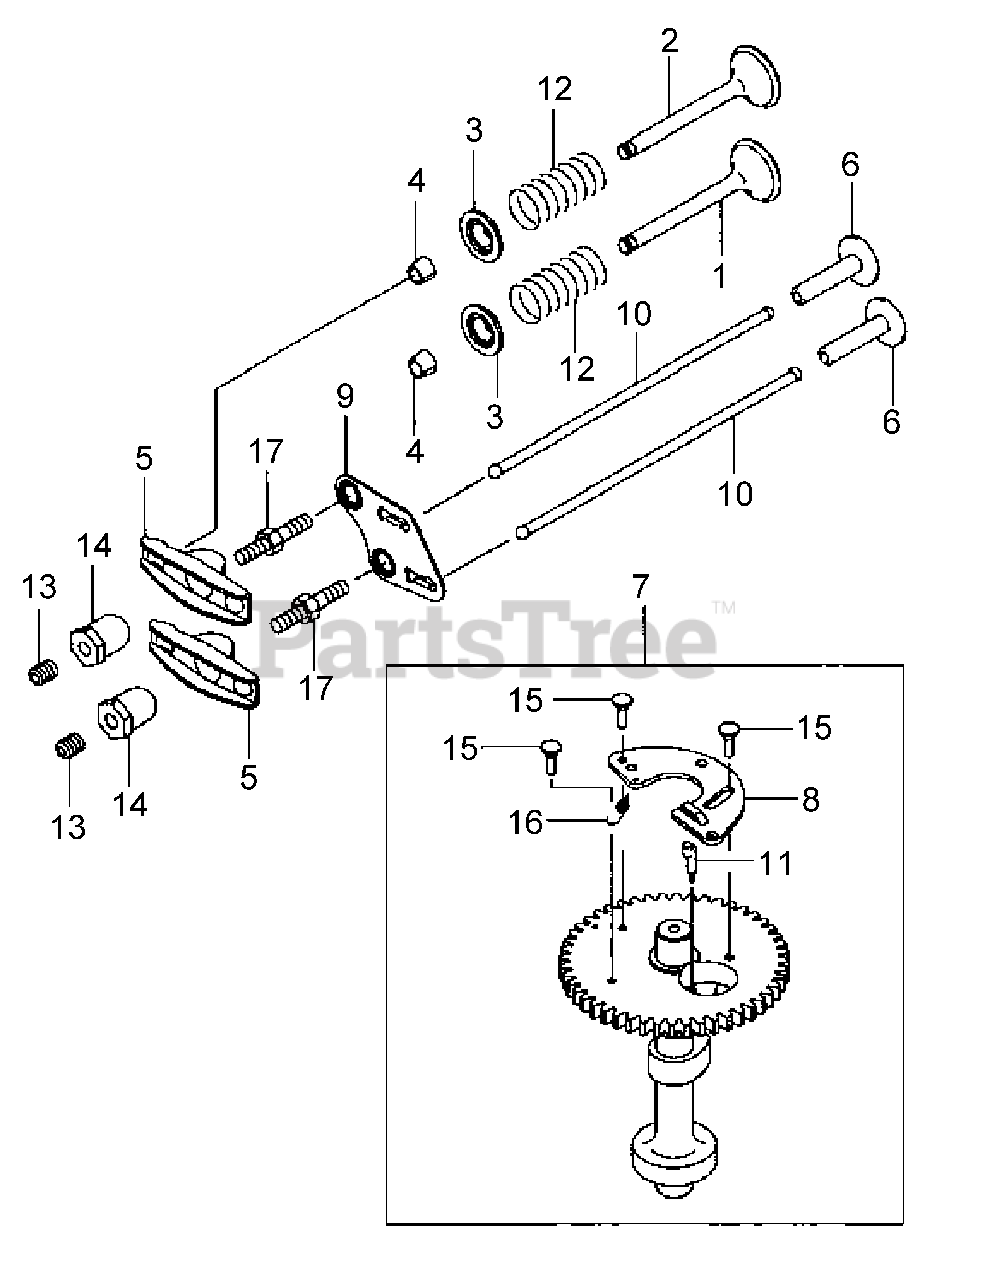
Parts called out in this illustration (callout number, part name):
1	Intake Valve
2	Exhaust Valve
3	Valve Spring Retainer
5	Rocker Arm
7	Camshaft Assy.
10	Push Rod
